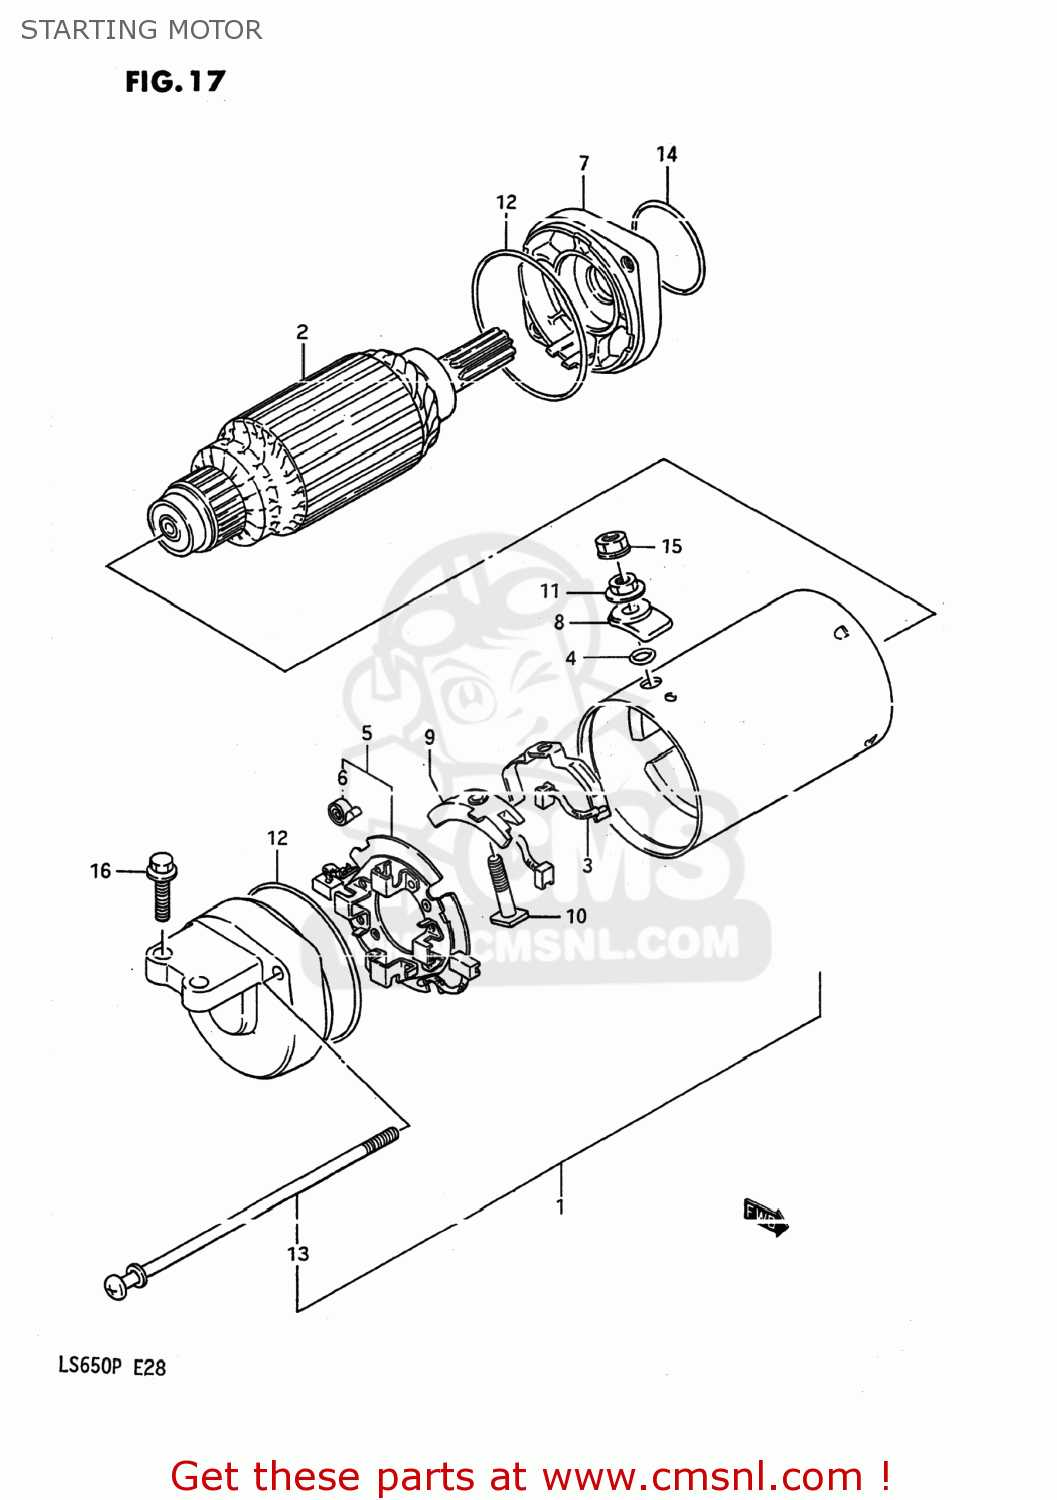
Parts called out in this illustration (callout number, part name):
1	MOTOR ASSEMBLY,STARTING
2	ARMATURE
3	TERMINAL SET,BRUSH
4	O RING
5	HOLDER SET,BRUSH(-)
6	SPRING
7	HOUSING ASSEMBLY,STARTER
8	BUSHING
9	BUSHING
10	BOLT
11	NUT
12	O RING
13	BOLT
14	O-RING (D:2.0)
15	NUT
16	BOLT
